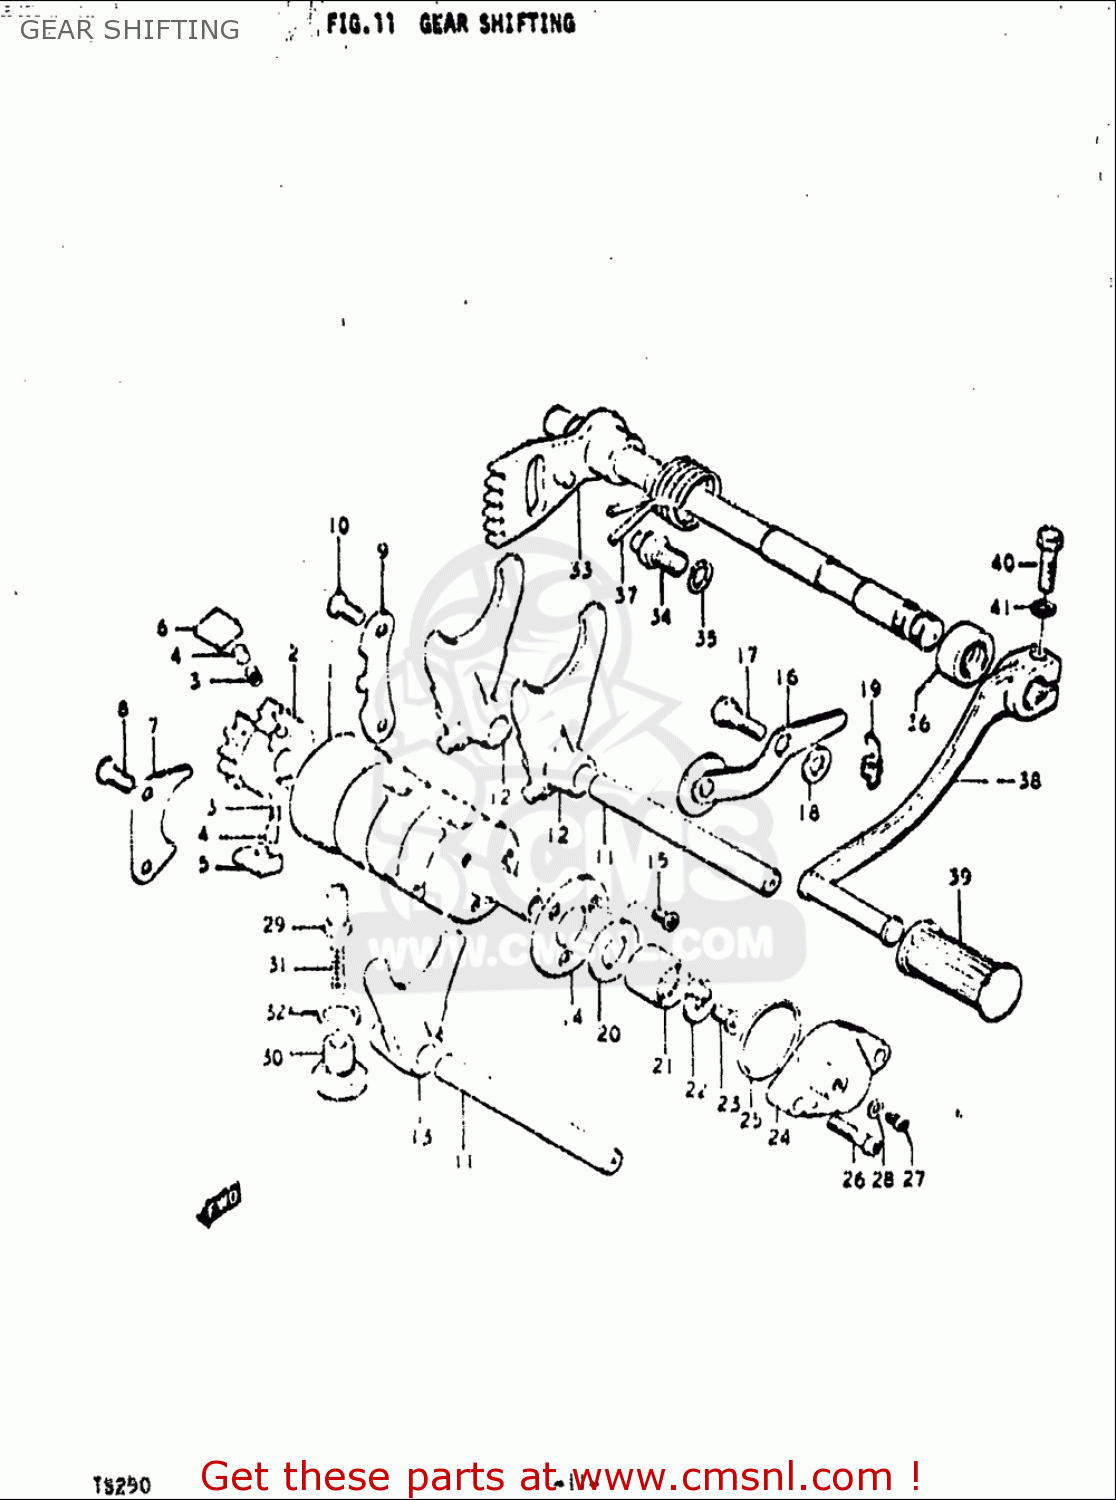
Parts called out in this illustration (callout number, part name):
2	GEAR,GEAR SHIFT CAM DRIVEN
3	SPRING
4	PIN(5X8)
5	PAWL,GEAR SHIFT NO.1
6	PAWL,GEAR SHIFT NO.2
7	LIFTER,GEAR SHIFT POLE
8	SCREW
10	SCREW
11	SHAFT,GEAR SHIFT FORK
15	SCREW
17	BOLT(6X16.1)
18	WASHER (6.5X13X1)
19	SPRING
22	CONTACT,GEAR SHIFT SWITCH
23	SCREW
24	BODY,GEAR SHIFT SWITCH
25	O RING(D:1.9,ID:27.7)
26	SCREW
27	SCREW
28	WASHER
29	STOPPER,GEAR SHIFT CAM NO.2
30	HOLDER,GEAR SHIFT CAM STOP SPR
31	SPRING
32	GASKET(14X19.2X2) (NAS)
33	SHAFT,GEAR SHIFT
34	STOPPER,GEAR SHIFT ARM
35	WASHER,LOCK
36	SEAL,OIL (12X22X9)
37	SPRING
38	LEVER ASSY,GEAR SHIFT
39	RUBBER,GEAR SHIFT PEDAL
40	BOLT
41	WASHER,LOCK
